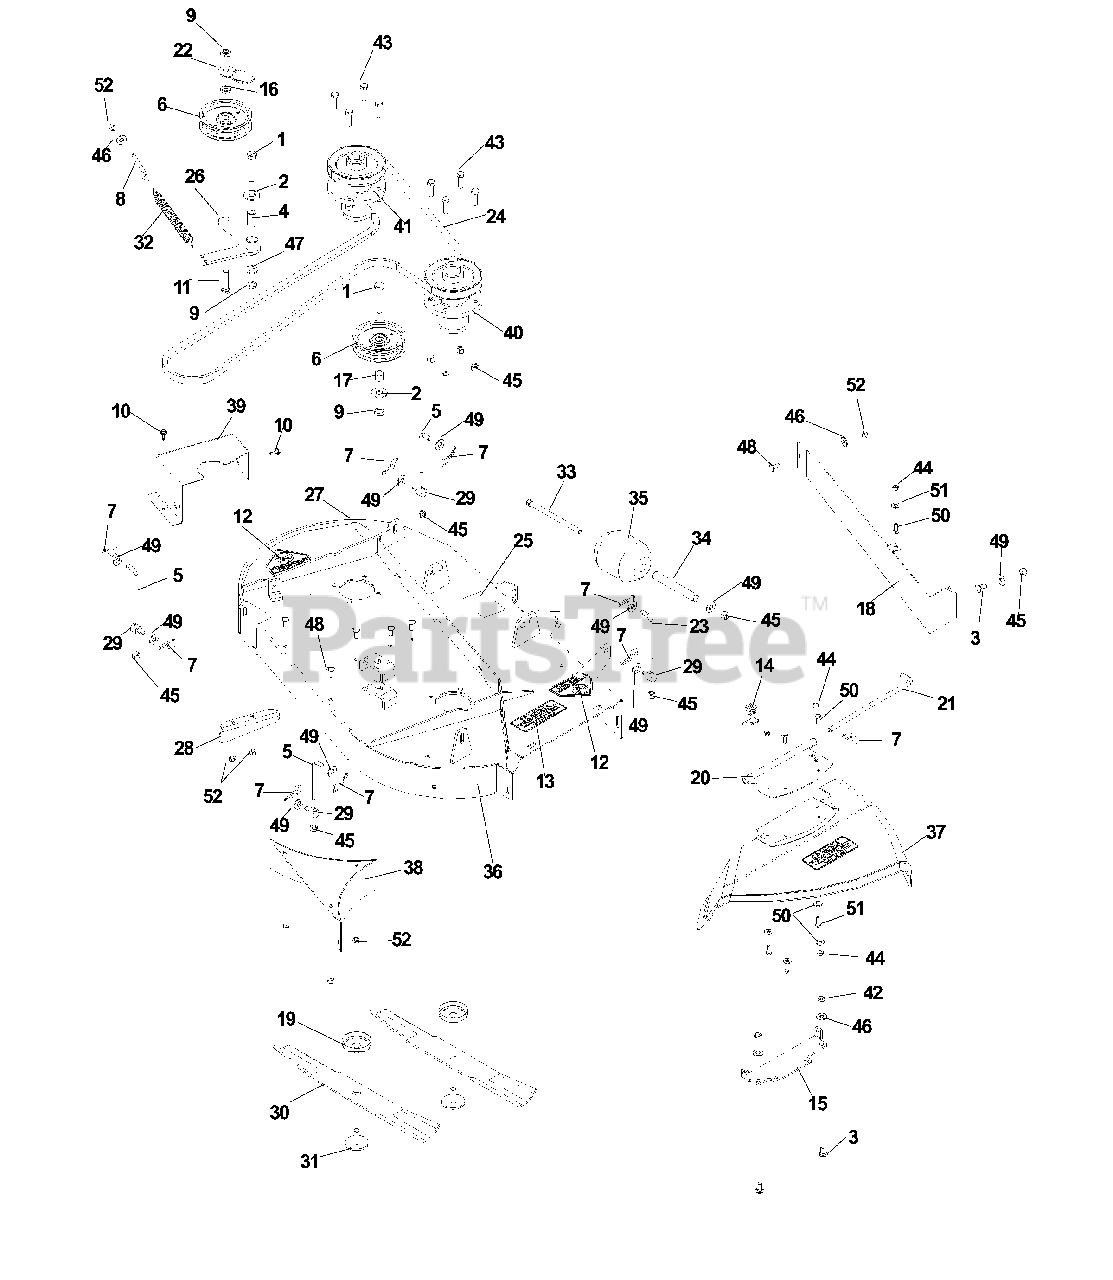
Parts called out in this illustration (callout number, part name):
1	HEX SCREW 1/2-13 X 2.5" GR 5
2	WASH USS FLAT 1/2
3	RHSNB 3/8-16 X 3/4 GR5 ZD
4	BUSHING DIXON 1080
5	L ROD 3-7/8
6	PULLEY IDLER
7	PIN, COTTER 1 3/4
8	EYE BOLT 5/16 X 3.50
9	NUT, 1/2-13 THIN PROF NYL
10	SCREW, TAP & DR #12-14 X 3/4
11	STUD 1/2-13 X 2
12	DECAL, CPSC
13	DECAL, DANGER
14	DEFLECTOR SPRING
16	HD PULLEY SPACER
17	BUSHING
19	TRASH GUARD
20	DEFLECTOR MT BRKT
21	DEFLECTOR PIN
22	BELT GUARD BLK
23	L-ROD 4.25
25	DECAL, BELT ROUTING
26	IDLER ARM WLDT., BLACK
27	DECAL, DECK 36"
28	BAFFLE DECK
30	BLD 36" HI LIFT FUS
31	BLADE BOLT
32	SPRING, DECK BELT
33	BOLT 3/8 X 6 GR5
34	BUSHING
35	ROLLER 3-3/4 DIA. X 4-1
36	DECK W/V-BAFFLE 36" DIX
37	PLASTIC DEFLECTOR 36
38	BAFFLE WLDT
39	PULLEY GUARD
40	HUB ASM RH
41	HUB ASM LH
42	NUT HEX 3/8-16 NYLON, THIN
43	HCS 3/8C X 1 1/4 GR5
44	NUT 1/4-20 NYLOC
45	NUT 3/8-16 NYLOC
46	FLAT WASHER 5/16 SAE
47	WASHER 1/2" FLAT
48	BOLT 5/16C X 3/4" CARRIAGE
49	WASHER 3/8 FLAT
50	HCS 1/4C X 3/4 HCS
51	WASHER 1/4 FLAT
52	NUT 5/16 NYLOC
